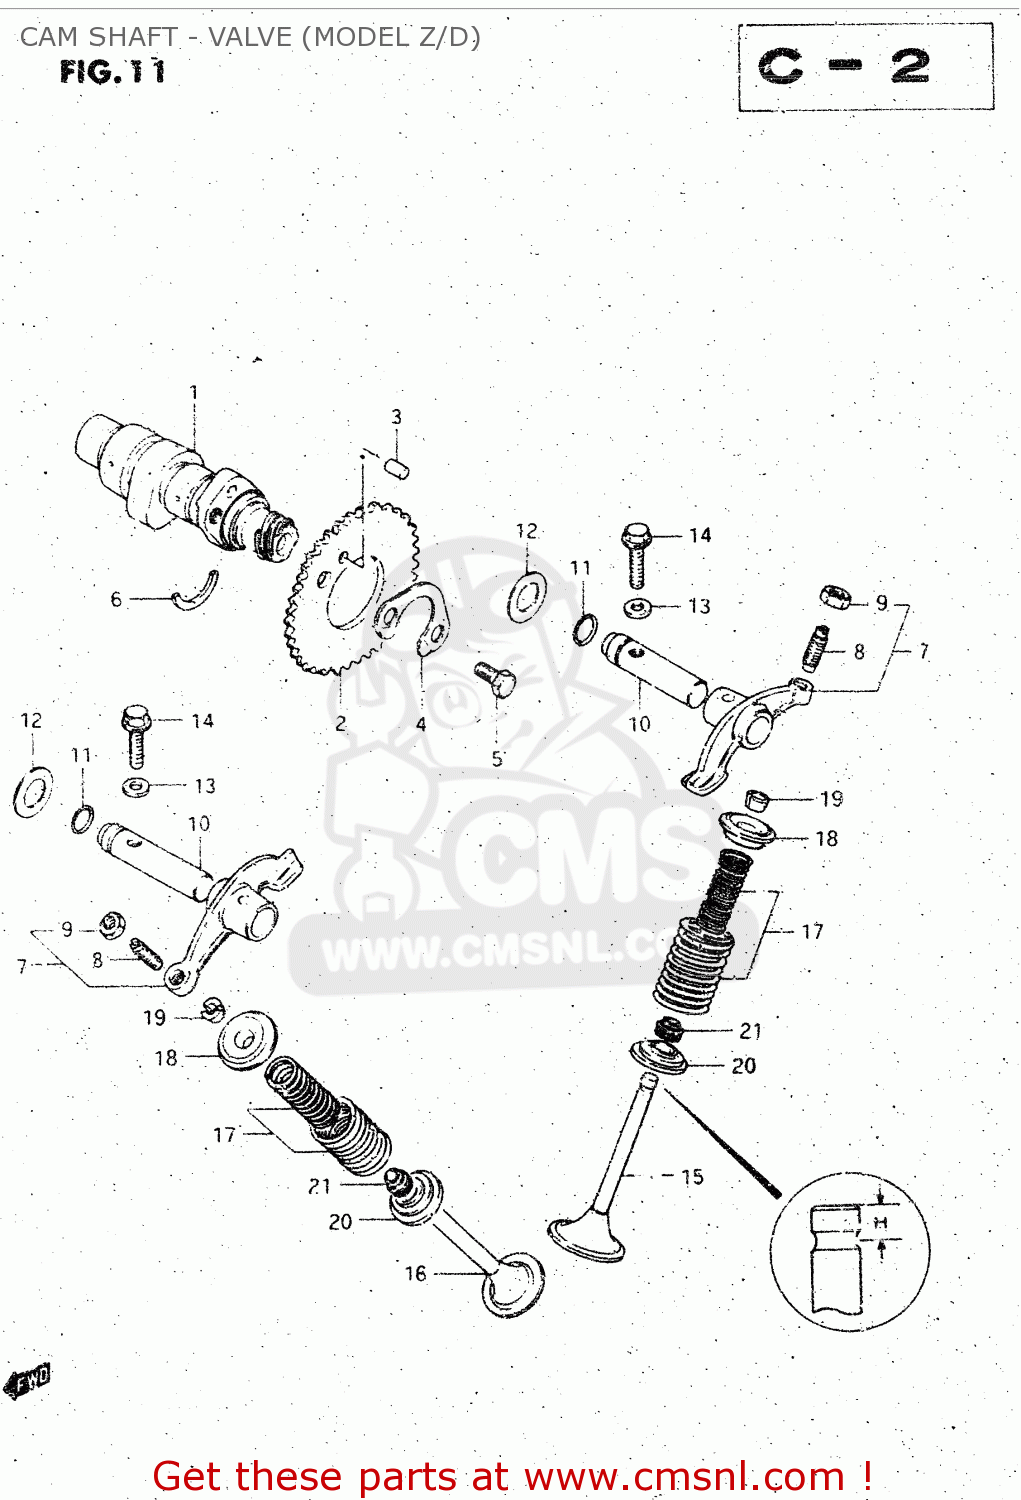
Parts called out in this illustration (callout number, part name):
1	CAMSHAFT
2	SPROCKET,CAMSHAFT
3	PIN(5X8)
4	WASHER,SPROCKET
5	BOLT(6X10.5)
6	C RING
7	ARM,VALVE ROCKER
8	SCREW,TAPPET ADJUSTING
9	NUT,ADJUSTING SCREW
10	SHAFT,VALVE ROCKET
11	O-RING
12	WASHER
13	GASKET(5.8X13X1.2) (NAS)
14	BOLT
15	VALVE,INTAKE
16	VALVE,EXHAUST
17	SPRING SET,VALVE
18	RETAINER,VALVE SPRING
19	COTTER VALVE
20	SEAT,VALVE SPRING
21	OIL SEAL
